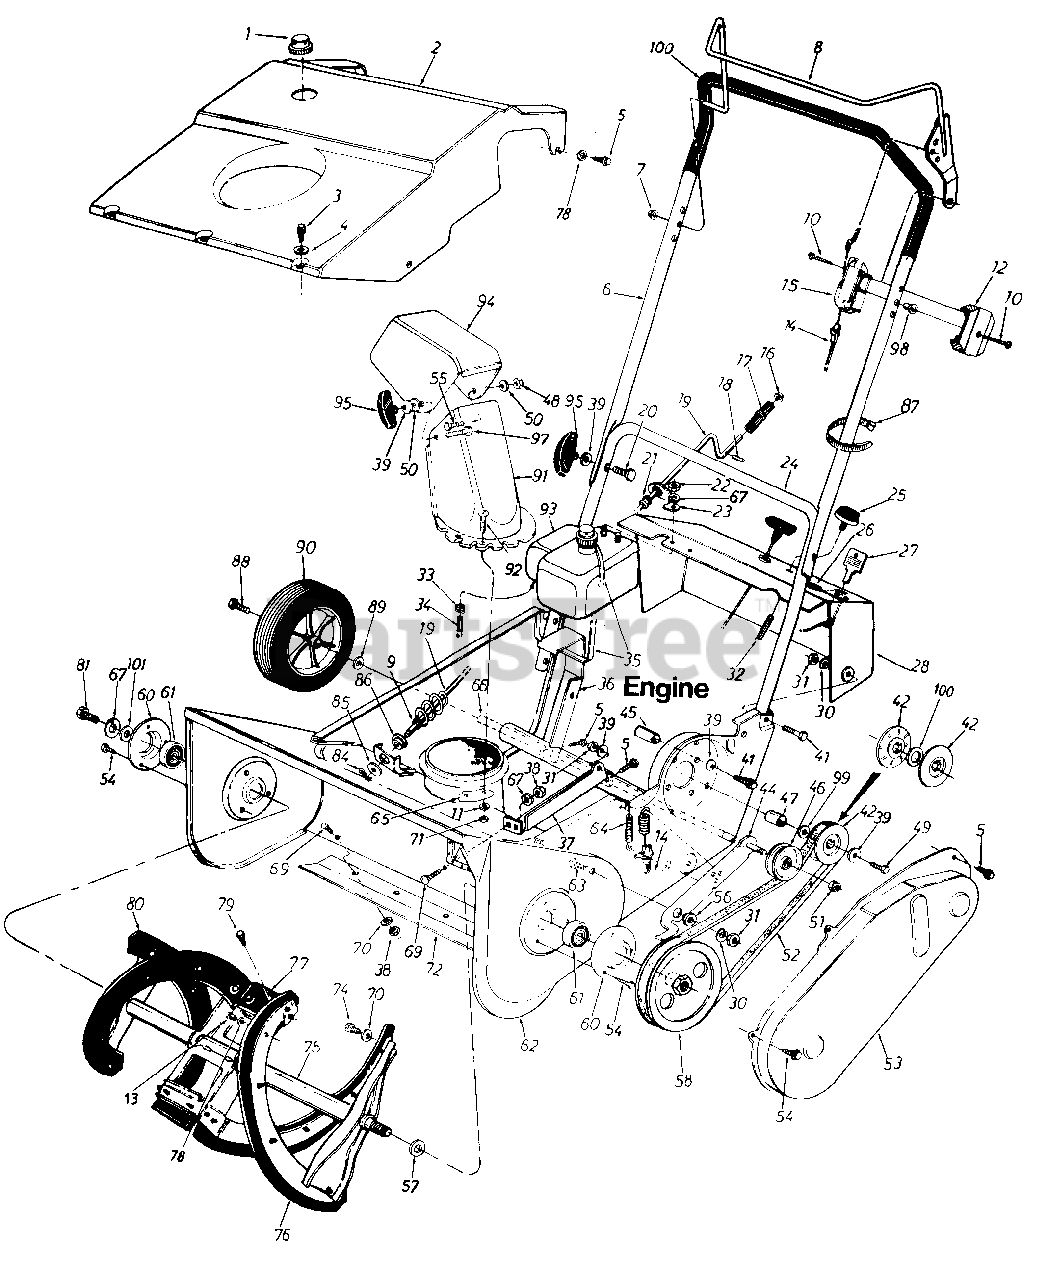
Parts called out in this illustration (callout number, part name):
1	Gas Tank Cap
2	21" Shroud
3	Hex B-Tap Scr. #10 x .38"
4	Spr.-Wash. .206" I.D. x .448"
5	Hex L-Wash. Hd. AB-Tap 1/4 x.62" Lg.
8	Control Handle Ass'y. L.H.
9	Fl-Wash. .385" I.D. x .62"
10	Truss Mach. Hi-B Tap Scr. #12 x 1.5" Lg.
11	Fl-Wash. .281" I.D. x .5 O.D.
12	Control Panel Half
13	Pop Rivet .188" Dia.
14	Clutch Cable 35" Lg.
15	Control Panel Half
16	Push Cap 3/8" Rod
17	Knob 3/8" Dia. Hole
18	Roll Pin 1/8" Dia. x .63" Lg.
19	Chute Crank Ass'y.
20	Curved Carriage Bolt 5/16-18 x 1.75" Lg.
21	Chute Crank Grommet
22	Hex Nut 1/4-20 Thd.
23	Upper Chute Crank Brkt.
24	Lower Handle
25	Primer
26	Plastic Plug
27	Plastic Key
30	L-Wash. 5/16" I.D.
31	Hex Nut 5/16-18 Thd.
32	Primer Hose 11" Lg.
33	Hose Clamp 1/2" Dia.
34	Gas Line 15"Lg.
35	Cable Tie 17.75" Lg.
36	Engine Support Brkt.
37	Engine Support
38	Hex Jam Nut 1/4-20 Thd.
39	Bell-Wash. .345" I.D. x .88"
41	Hex Bolt 5/16-18 x 1.5" Lg.
42	3/8" "V"-Pulley Half .625" I.D. x 6.0" O.D.
44	Idler Brake Brkt. Ass'y.
45	Spacer .325" I.D. x .625" O.D. x .875"
46	Fl-Idler w/Flanges 2.12" O.D.
47	Spacer .635" I.D. x .89" O.D. x .57"
48	Hex L-Nut 5/16-18 Thd.
49	Hex Bolt 5/16-24 x .75" Lg.
50	Fl-Wash. .344" I.D. x 1.25"
51	Hex Patch L-Nut 3/8-24 Thd.
52	"V"-Belt
54	Hex B-Tap Scr. 1/4" X .38" Lg.
55	Carriage Bolt 5/16-18 x .75"
56	Shld. Spacer .50" Dia. x .27"
57	Fl-Wash. .510" I.D. x 1.0" O.D.
58	3/8" "V"-Pulley 1/2-20 L.H. x 6"
64	Extension Spring 1.12" Lg.
65	Chute Flange Keeper
66	Wheel Axle 1/2" O.D. x 20.6" Lg.
67	L-Wash. 1/4" I.D.
69	Carriage Bolt 1/4-20 x .50"
70	Fl-Wash. .281" I.D. x .73"
71	Hex L-Nut 1/4-20 Thd.
72	Shave Plate
74	Hex Wash. B-Tap Scr. 1/4 x .62"
76	Rubber Spiral L.H.
77	Rubber Paddle
78	Fl-Wash. .218" I.D. x .62"
79	Hex Wash. B-Tap Scr. #10 x .62" Lg.
80	Rubber Spiral R.H.
81	Hex Wash. TT-Tap Cl-Scr. 1/4-20 x .75" Lg.
84	Cotter Pin 3/32" Dia. x .75"
85	Fl-Wash. .406" I.D. x 1.25"
86	Hex Bushing .385" I.D.
87	Cable Tie
88	Hex Tap Scr. 3/8-24 x .88" Lg.
89	Fl-Wash. .510" I.D. x .75"
90	Wheel & Tire Ass'y. 7" x 1.5"
91	Lower Chute
92	Truss Mach. Scr. 1/4-20 x .75"
93	Fuel Tank Two Qt.
94	Upper Chute
95	Knob Handle Ass'y.
97	Carriage Bolt 5/16-18 x 1"
98	Control Disc Pin
99	Fl-Wash. .635" I.D. x 1.04' O.D.
100	Fl-Wash. .635" I.D. x 1.0" O.D.
101	Fl-Wash. .25" I.D. x .93"
